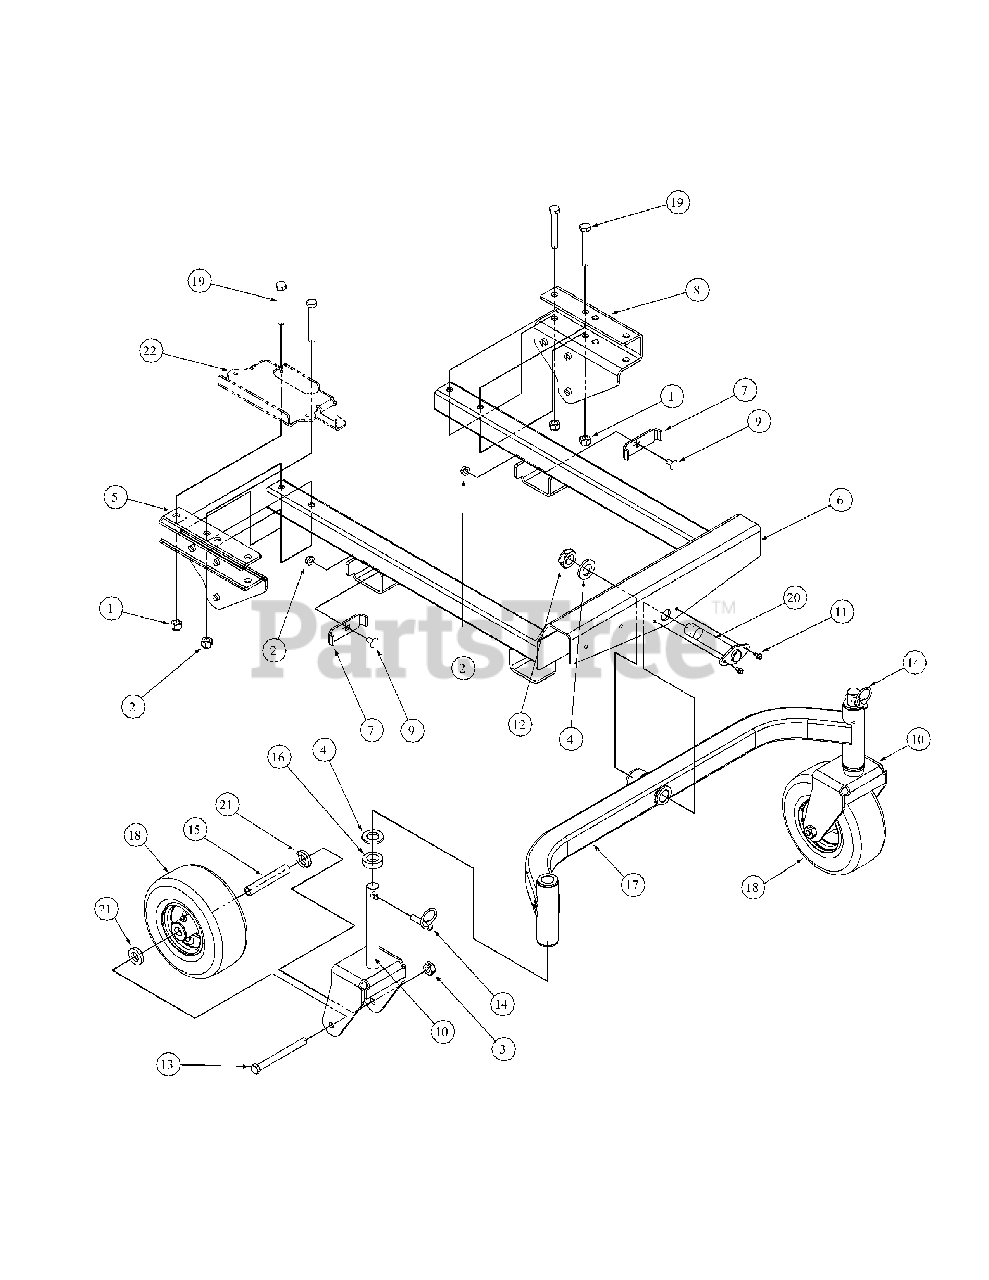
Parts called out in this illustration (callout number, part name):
1	Hex Jam Nut 1/2-13
2	Nut, Hex 3/8-16 Flange Lock
3	Nut, 1/2-20, Center Lock
4	Washer Special
5	Support Brack Frame Right Hand
6	Front Frame Assembly
7	Plate Wear
8	Bracket Support Frame, Left Hand
9	Carrige Bolt, 3/8-16 x .75 LG.
10	Caster Assembly
11	Screw, TT, 1/4-20, 0.500, Hex Index
12	Nut, Jam, 1.0-14, Insert Lock
13	HHCS, 1/2-20, 5.50
14	Pin, Klik, 1.75 LG
15	Spacer Wheel
16	Spacer, 1.015 ID x 1.62 OD x .50
17	Front Axle Assembly, Flange Bearing
18	Wheel Assembly 9.0 x 3.50 -4
19	Hex Cap Screw, 1/2-13 x 3.25
20	Pin Assembly, Plated
21	Spacer, .790 ID x .347 LG
22	Battery Bracket
